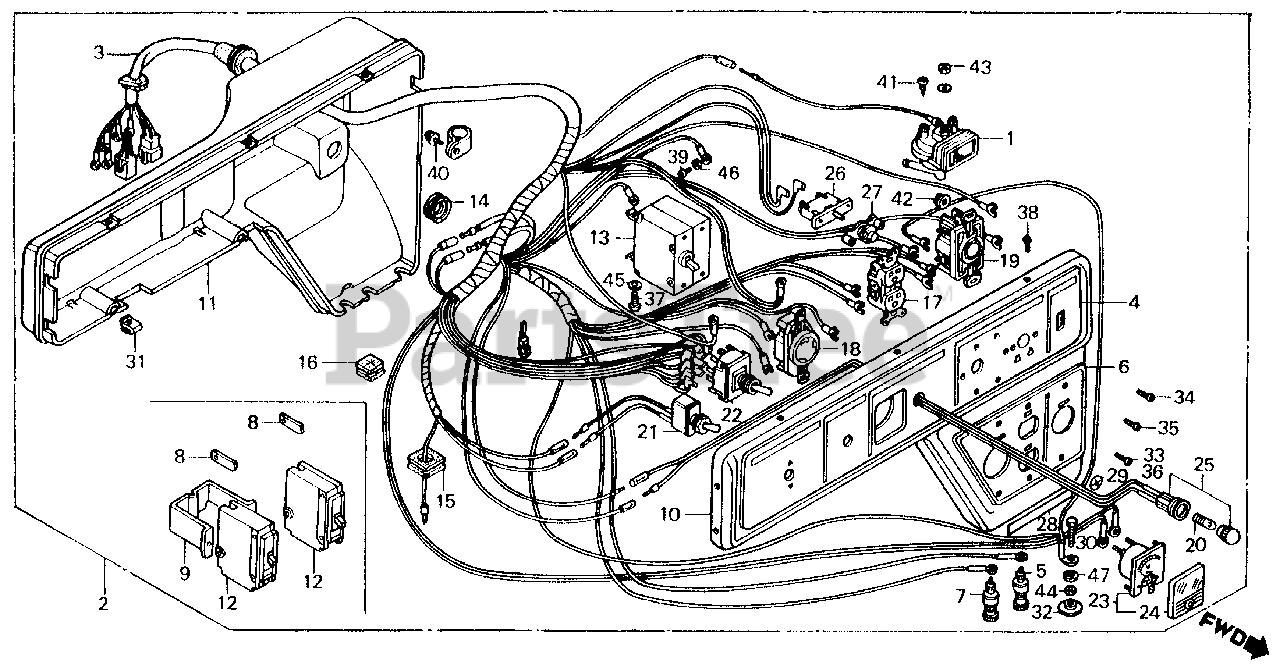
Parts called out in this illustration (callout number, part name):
1	SWITCH ASSY., UNIT
2	BOX ASSY., CONTROL *R8* (BRIGHT RED)
3	WIRE HARNESS ASSY.
4	MARK, SWITCH PANEL
5	TERMINAL, D.C. OUT (+)
6	MARK, A.C. OUTPUT
7	TERMINAL, D.C. OUT (-)
8	TERMINAL, BREAKER
9	SUPPORT, BREAKER (NOT AVAILABLE)
10	PANEL, CONTROL *R8* (EM-A) (BRIGHT RED)
10	PANEL, CONTROL *R8* (BRIGHT RED) (NOT AVAILABLE)
11	CASE, CONTROL (NOT AVAILABLE)
12	BREAKER, CIRCUIT (12.5A) (NOT AVAILABLE)
13	BREAKER, CIRCUIT (12.5A) (NOT AVAILABLE)
14	GROMMET, UNIT SWITCH
15	GROMMET, SWITCH WIRE
16	GROMMET, WIRE
17	RECEPTACLE ASSY. (125V-20A)
17	RECEPTACLE (20A/125V)
18	RECEPTACLE (3-PRONG) (30A/125V)
19	RECEPTACLE (20A/125-250V)
20	BULB (24V2W)
21	SWITCH ASSY., ENGINE (NOT AVAILABLE)
22	SWITCH ASSY., VOLT CHANGE
23	VOLTMETER ASSY.
24	LENS, METER
25	SOCKET ASSY., PILOT LAMP
26	PROTECTOR, CIRCUIT (DC)
27	LENS ASSY., PROTECTOR
28	MARK, D.C. OUTPUT (NOT AVAILABLE)
29	MARK, GROUND
30	BOLT, HEX. (6X18)
31	NUT, SPRING (5MM)
32	NUT, SPECIAL (6MM)
33	SCREW, PAN (3X6)
34	SCREW, PAN (3X12)
35	SCREW, PAN (4X6)
36	SCREW, PAN (4X8)
37	SCREW, PAN (4X10)
38	SCREW, PAN (5X12)
39	SCREW, PAN (5X12)
40	SCREW-WASHER (5X10)
41	SCREW, TAPPING (5X10)
42	NUT, HEX. (4MM)
43	NUT, HEX. (5MM)
44	NUT, HEX. (6MM)
45	WASHER, SPRING (4MM)
46	WASHER, SPRING (5MM)
47	WASHER, SPRING (6MM)
